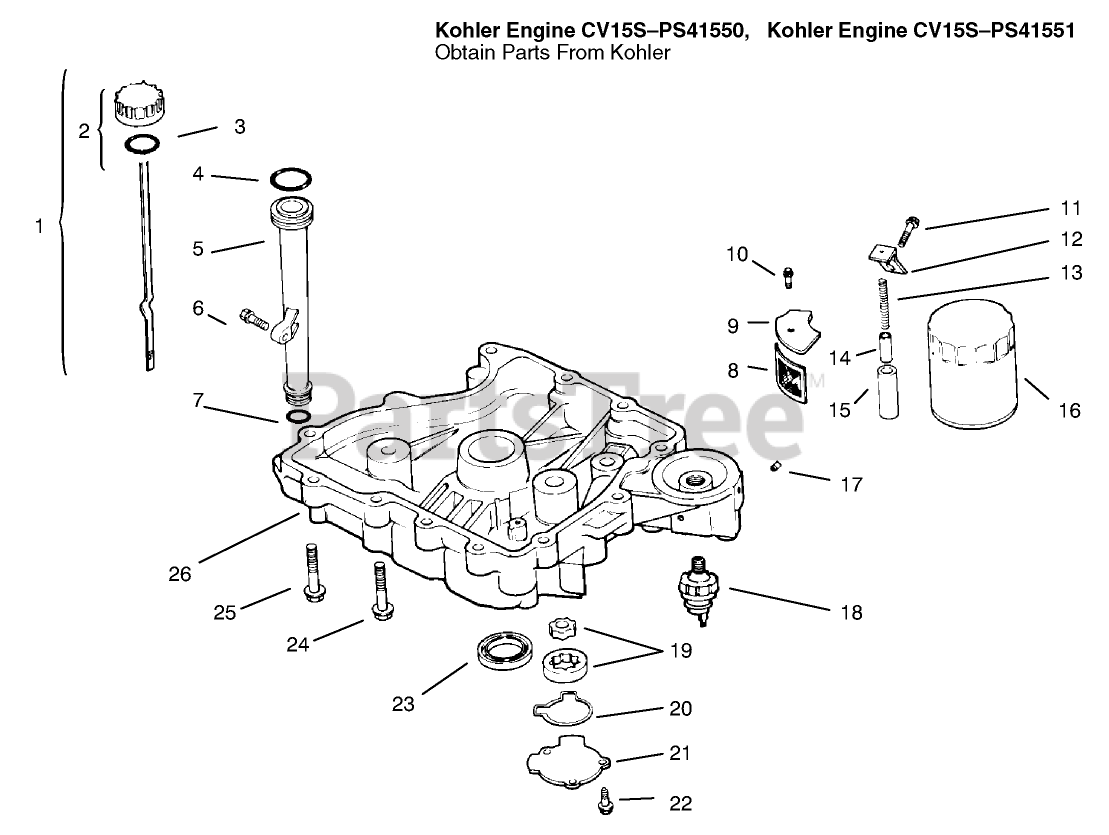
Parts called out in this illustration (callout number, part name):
1	Dipstick INC 2-3 (Only On: 72042, 72063, 72062, 72043)
2	Kit-Oil Fill Cap (Incl. Ref. #7)
3	ORing
4	O Ring-Upper Fill Tube (Only On: 72103)
5	Tube-Oil Fill (Only On: 72103, 72083)
7	O-Ring-Lower Fill Tube (Only On: 72042, 72063, 72062, 72043)
8	Screen-Oil Pickup
9	Cover-Oil Pickup Screen (Only On: 72042, 72063, 72062, 72043)
10	Screw M5x0.8x16 (Only On: 72042, 72063, 72062, 72043)
11	Screw M10x1.5x25 (Only On: 72042, 72063, 72062, 72043)
12	Bracket-Oil Pump Relief (Only On: 72042,72043,72062,72063)
13	Spring-Oil Relief Valve (Only On: 72042,72043,72062,72063)
14	Piston-Oil Relief Valve (Only On: 72042, 72063, 72062, 72043)
15	Body-Oil Relief Valve (Only On: 72042, 72063, 72062, 72043)
16	Filter-Oil
18	Switch-Oil Pressure
19	Pump-Oil (Only On: 72042, 72063, 72062, 72043)
20	O Ring-Oil Pump Cover (Only On: 72042,72043,72062,72063)
21	Cover-Oil Pump (Only On: 72042,72043,72062,72063)
22	Screw M5x0.8x16 (Only On: 72042, 72063, 72062, 72043)
23	Seal-Crankshaft (Only On: 72042, 72043, 72062, 72063)
25	Screw M8x1.25x45 (Only On: 72103, 72083)
26	Pan-Oil (Only On: 72042,72043,72062,72063)
